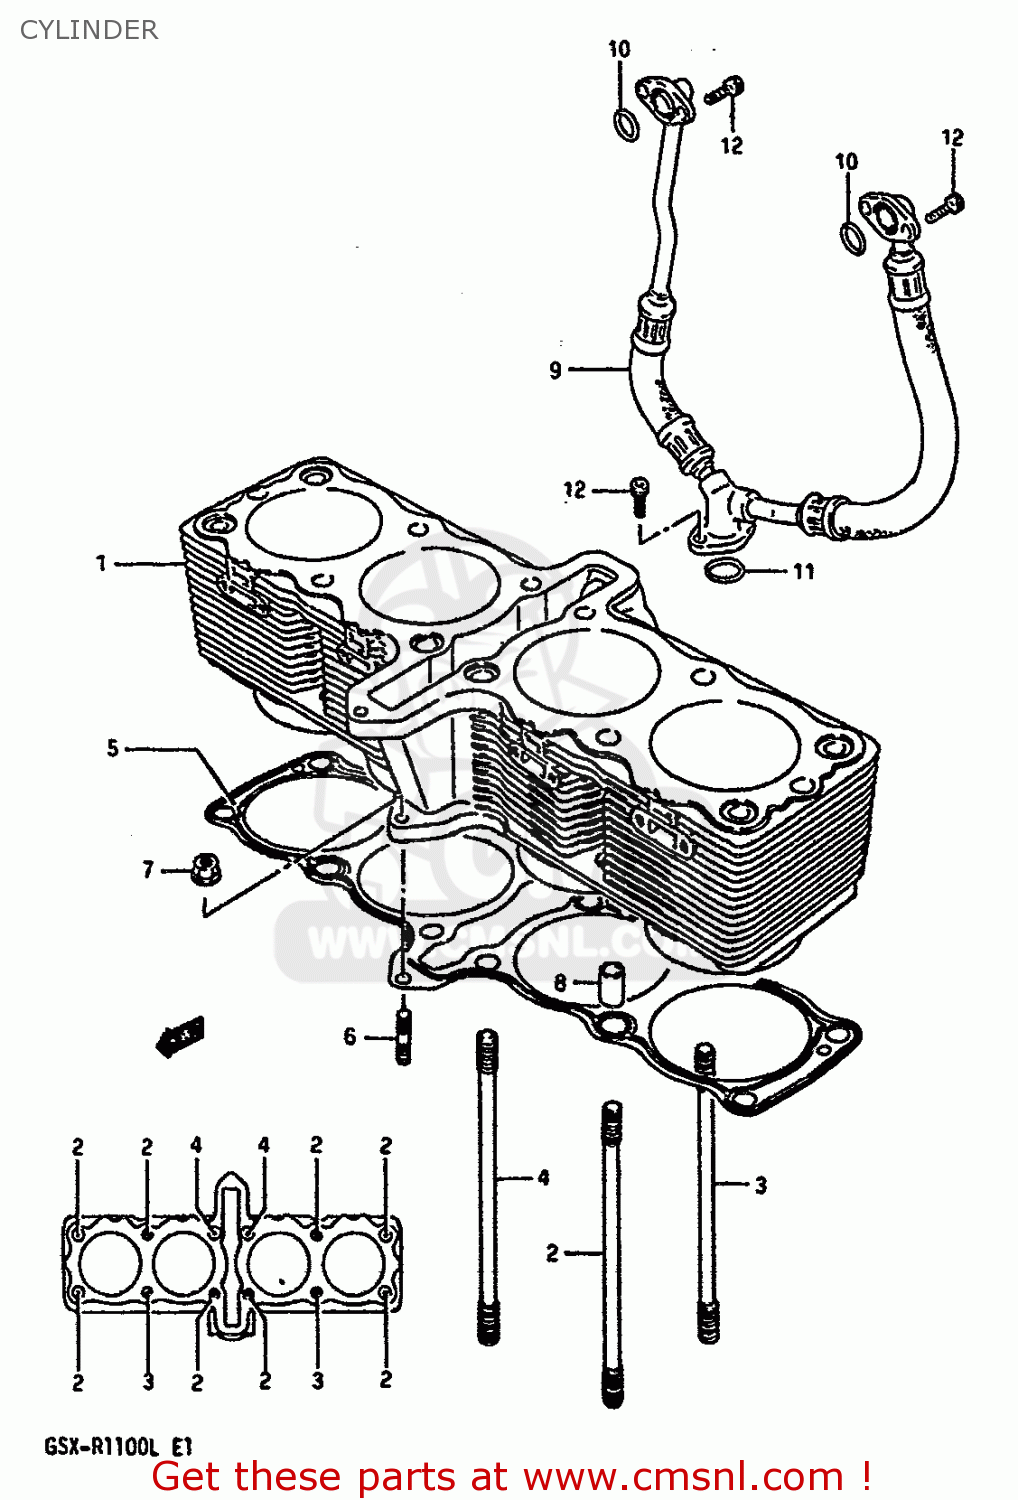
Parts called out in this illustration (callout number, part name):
1	CYLINDER
2	BOLT,STUD
3	BOLT,STUD
4	BOLT,STUD
5	GASKET,CYLINDER (NAS)
6	STUD BOLT L:20
7	NUT 6MM
8	PIN
9	HOSE
10	O RING(D:2.5,ID:13.8)
11	O RING(D:2.4,ID:15.8)
12	BOLT
